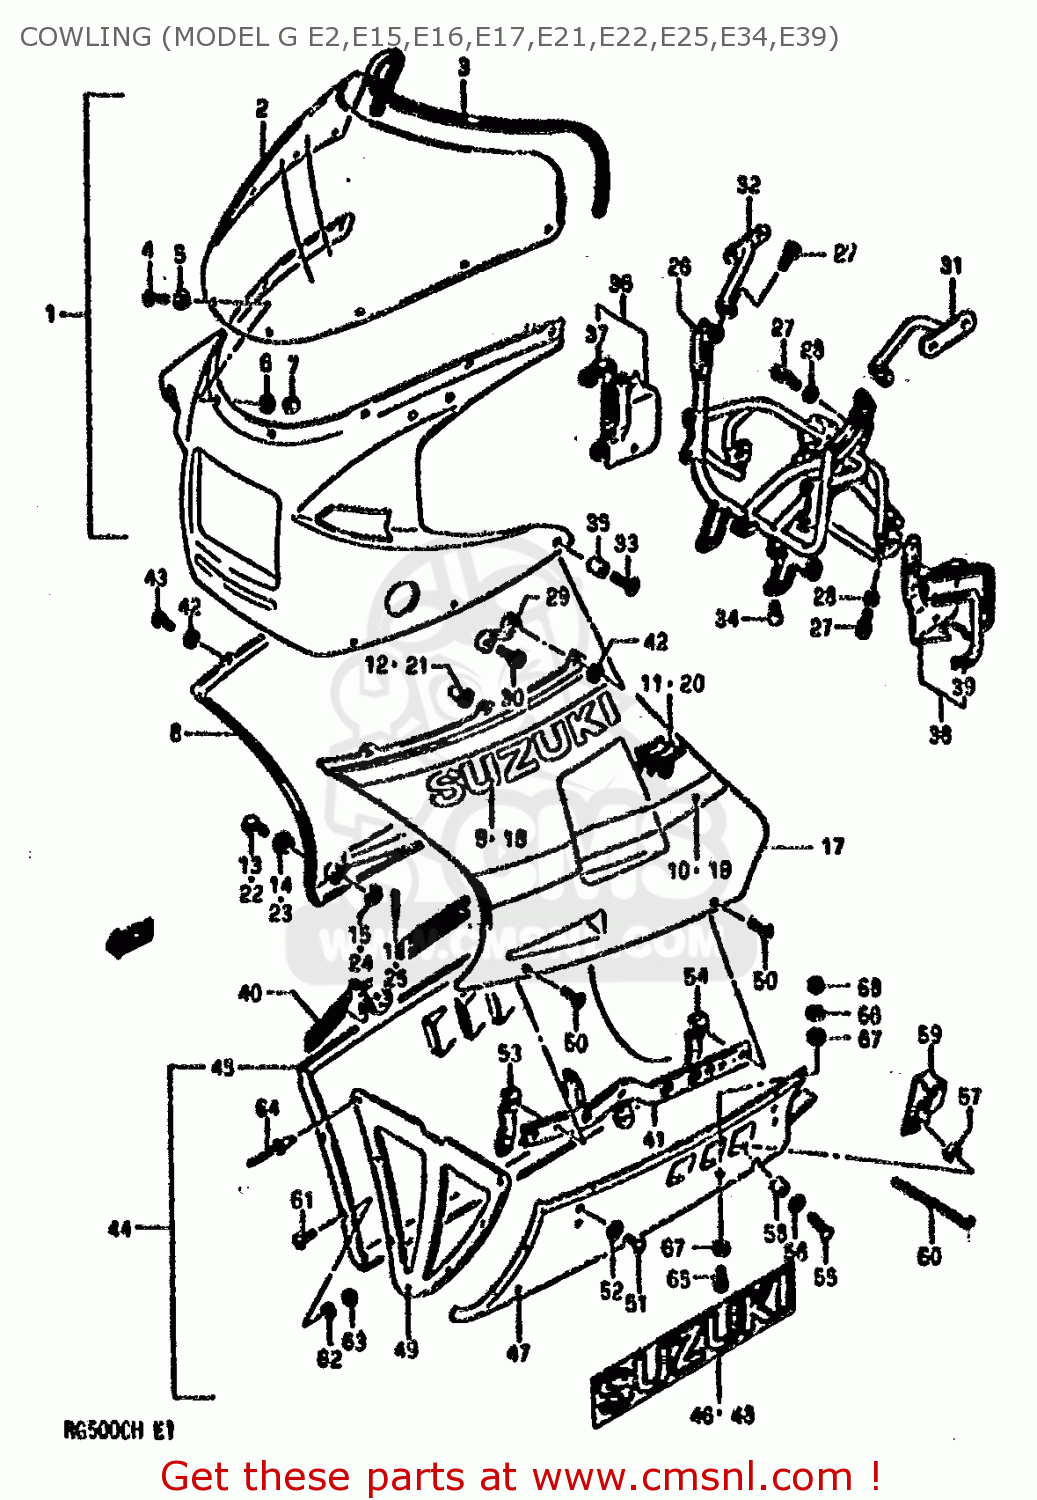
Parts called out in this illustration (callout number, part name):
1	COWLING ASSY (BLUE)
2	WINDOW,COWLING
3	MOLDING
4	SCREW(5X14)
5	CUSHION
6	WASHER,5MM
7	NUT 8MM
8	COWLING,RH
9	EMBLEM
10	TAPE,SET,RH
11	EMBLEM,FRAME COVER
12	NUT,COWLING COVER
13	HEAD,COWLING FASTENER
14	WASHER,COWLING FASTENER
15	E-RING
16	PIN
17	COWLING LH
18	EMBLEM
19	TAPE SET,LH
20	EMBLEM,FRAME COVER
21	NUT,COWLING COVER
22	HEAD,COWLING FASTENER
23	WASHER,COWLING FASTENER
24	E-RING
25	PIN
26	BRACE,COWLING
27	BOLT
28	WASHER,LOCK,8.
29	BRACKET,COWLING UPR
30	BOLT
31	BRACKET,RR VIEW MIRRORR,L
32	BRACKET,RR VIEW MIRRORR,R
33	SCREW(6X25)
34	SCREW(6X16)
35	SPACER
36	COVER,COUPLER RH
37	MOLDING
38	COVER,COUPLER LH
39	MOLDING
40	BRACKET,COWLING LWR,R
41	BRACKET,COWLING LWR,L
42	WASHER(7X14X1.2)
43	SCREW(6X30)
44	COWLING,UNDER (BLUE)
45	COWLING,UNDER RH
46	EMBLEM
47	COWLING,UNDER LH
48	EMBLEM
49	COVER,CENTER
50	SCREW(6X12)
51	SCREW
52	WASHER
53	BRACKET
54	BRACKET
55	SCREW
56	WASHER 6MM
57	CUSHION
58	SPACER
59	BRACKET
60	CLAMP
61	SCREW
62	WASHER
63	NUT 4MM
64	RIVET
65	SCREW
66	WASHER
67	WASHER
68	NUT
